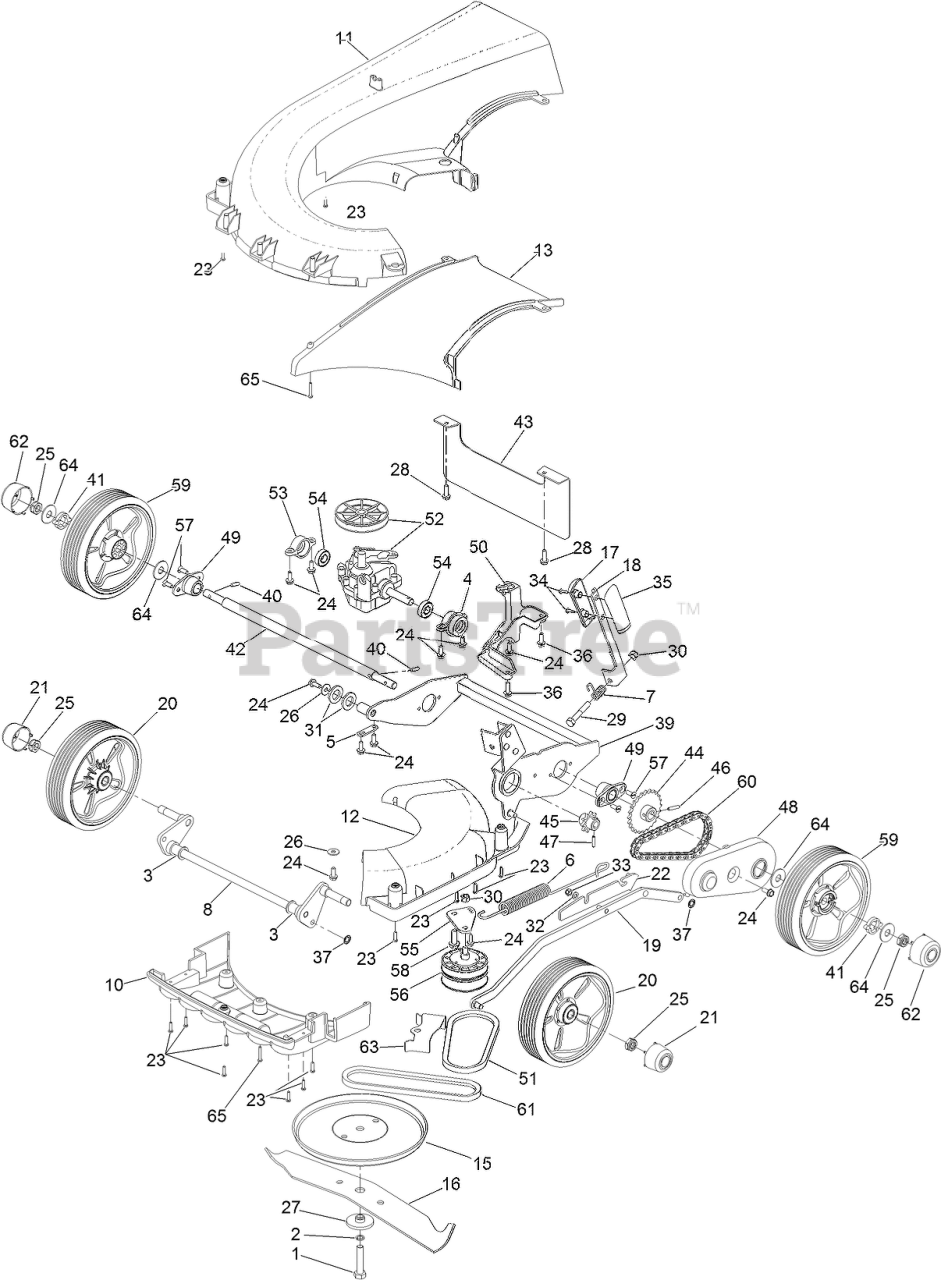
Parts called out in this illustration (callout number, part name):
1	BOLT-UNF
2	WASHER-SPRING
3	BEARING-AXLE, FRONT
4	HOUSING-PIVOT BEARING, LH
5	PLATE-SECURING
6	SPRING-COUNTER BALANCE
7	SPRING-HOC
8	AXLE-FRONT
10	MOULDING-FIN
11	MOULDING-SNAIL DECK
12	MOULDING-ACCESS, SNAIL DECK
13	MOULDING-THROW PLATE
15	DISC-FRICTION
16	CUTTERBAR
17	KNOB-HOC, RH
18	LEVER-HOC
19	ROD-CONNECTING BAR
20	WHEEL ASM
21	CAP-WHEEL, CENTER
22	MOUNT-SPRING
24	SCREW-TAPTITE
25	NUT-NYLOC
26	WASHER
27	SPACER-DISTANCE, CUTTERBAR
28	SCREW-TAPTITE
30	NUT-HEX, NI
31	WASHER-PLAIN
32	WASHER-PLAIN
33	NUT-NYLOC
35	KNOB-HOC, LH
36	SCREW-HH
37	WASHER-STARLOCK
39	FRAME-REAR WHEEL
40	KEY-DRIVE
41	CAM-DRIVE
42	AXLE-REAR
43	GUARD-REAR
44	SPROCKET-24T
45	SPROCKET-GEARBOX
46	PIN-SPRING, SELLOC
47	PIN-ROLL
48	COVER-DRIVE
49	HOUSING-BEARING, ROLLER
50	MOUNT-BEARING
51	BELT-VARIATOR
52	GEARBOX ASM
53	HOUSING-GEARBOX, BEARING (RH)
54	BEARING
55	BRACKET-BELT
56	PULLEY VARIATOR ASM
57	SCREW-TAPTITE
58	SCREW-TAPTITE
59	WHEEL ASSEMBLY (DRIVE, GREY)
60	CHAIN-43 LINKS
61	BELT-VARIATOR (536)
62	CAP-DRIVE WHEEL
63	GUARD-BELT
64	WASHER-THRUST
